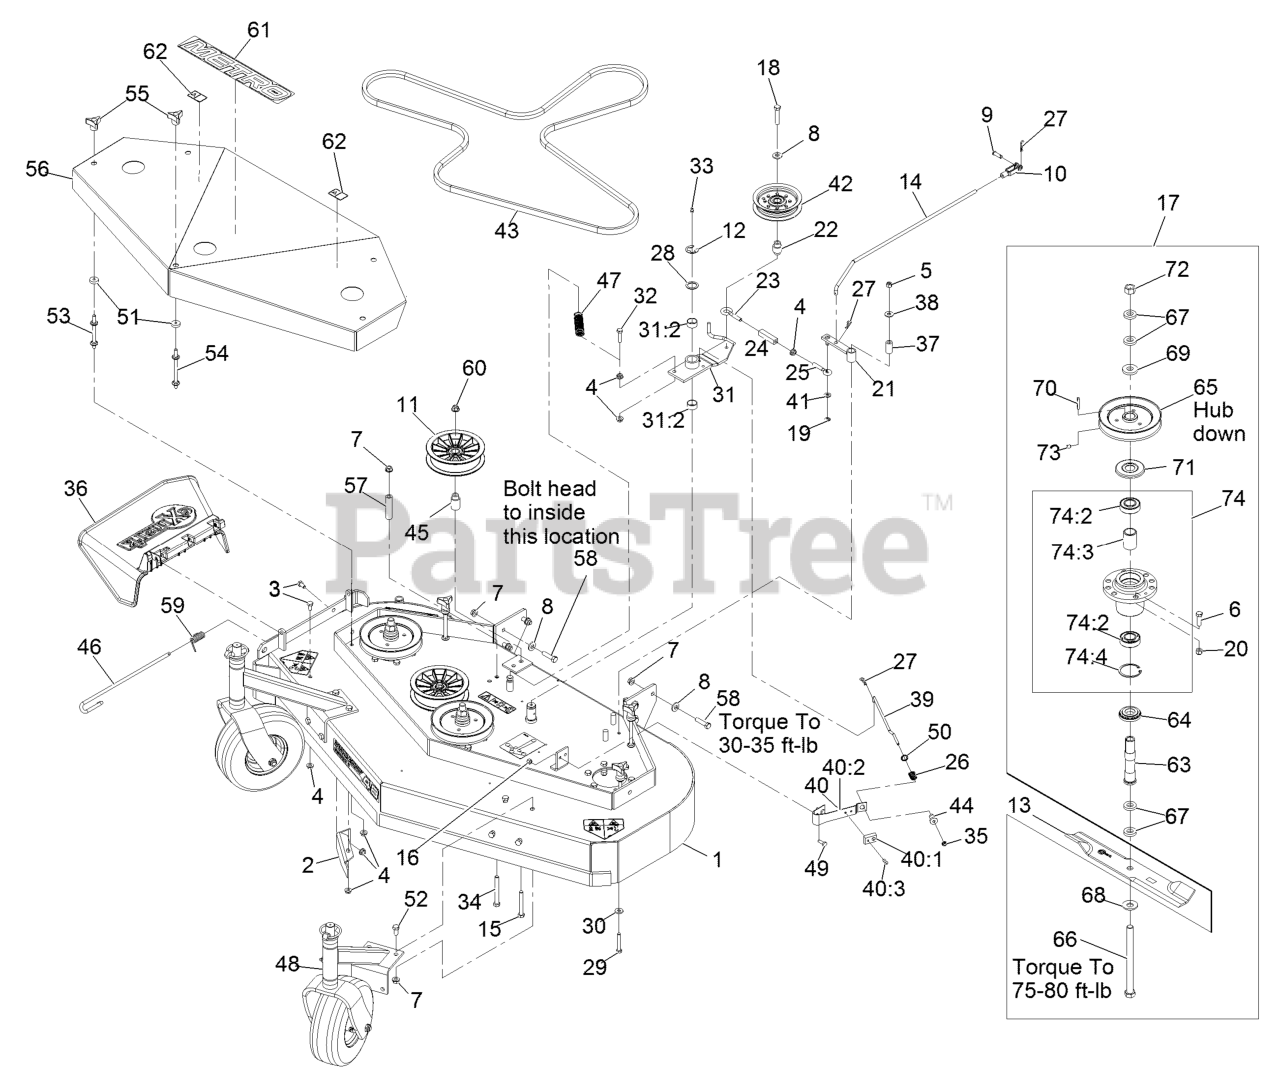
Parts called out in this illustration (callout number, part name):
1	DECK-SERVICE, 48
2	BAFFLE-DOGLEG
3	SCREW-HH
5	NUT-LOCK, NI
6	SCREW-HH
7	NUT-HHF, WHIZ
8	WASHER-BELLEVILLE
9	PIN-CLEVIS
10	YOKE-ADJUSTABLE
11	PULLEY,IDLER 5"
12	RING-RETAINING, EXT
14	ARM-ASSIST, LINKAGE
15	SCREW-HH
16	NUT-LOCK, NI
17	ASM, CUTTER HOUSING OUTER
18	SCREW-HH
19	RING-RETAINING, EXT
20	NUT-LOCK, NI
21	ARM-ASSIST, 32/36
22	BUSHING-ENGAGEMENT
23	EYEBOLT-THREAD, LH
24	BODY-TURNBUCKLE
25	EYEBOLT-THREAD, RH
26	SPRING-COMPRESSION
27	PIN-COTTER
28	WASHER-SPINDLE
29	SCREW-HH
30	WASHER-SPRING
31	IDLER ARM ASM
31:2	SLEEVE-BEARING
32	SCREW-HH, SPECIAL
33	FITTING-GREASE
34	SCREW-HH
35	NUT-LOCK, NI
36	CHUTE DEFLECTOR XRK M056
37	TUBE-PIVOT
38	WASHER-FLAT
39	ROD-BRAKE
40	PAD AND SPRING ASM
41	WASHER-PLAIN
43	BELT,BLADE 48
44	SPACER-FLANGED
45	BUSHING-IDLER
46	PIN-CHUTE
47	SPRING-EXTENSION
48	ASM-CASTER MNT W/WEIGHT
49	SCREW-HH
50	RING-PUSH ON
52	SCREW-HH
53	STUD-SHIELD, BELT (SHORT)
54	STUD-SHIELD, BELT (LONG)
55	KNOB-3 PRONG
56	ASM,SHIELD W/DECALS 48 ME
58	SCREW-HH
59	SPRING, TORSION
60	NUT-HF, NI
61	Decal-Metro
62	DECAL-WARNING
63	TUBE-SPINDLE, SHORT
64	SPACER-GUARD, BOTTOM
65	SHEAVE
66	SCREW-CAP, HH
68	WASHER-SPRING
69	WASHER-RETAINER, SHEAVE
71	GUARD-BEARING, TOP
72	NUT-HEX
73	SETSCREW
74	Cutter Housing ASM
74	KIT, CUTTER HOUSING
74:2	BEARING-JACKSHAFT
74:3	SPACER-BEARING
74:4	RING-SNAP
